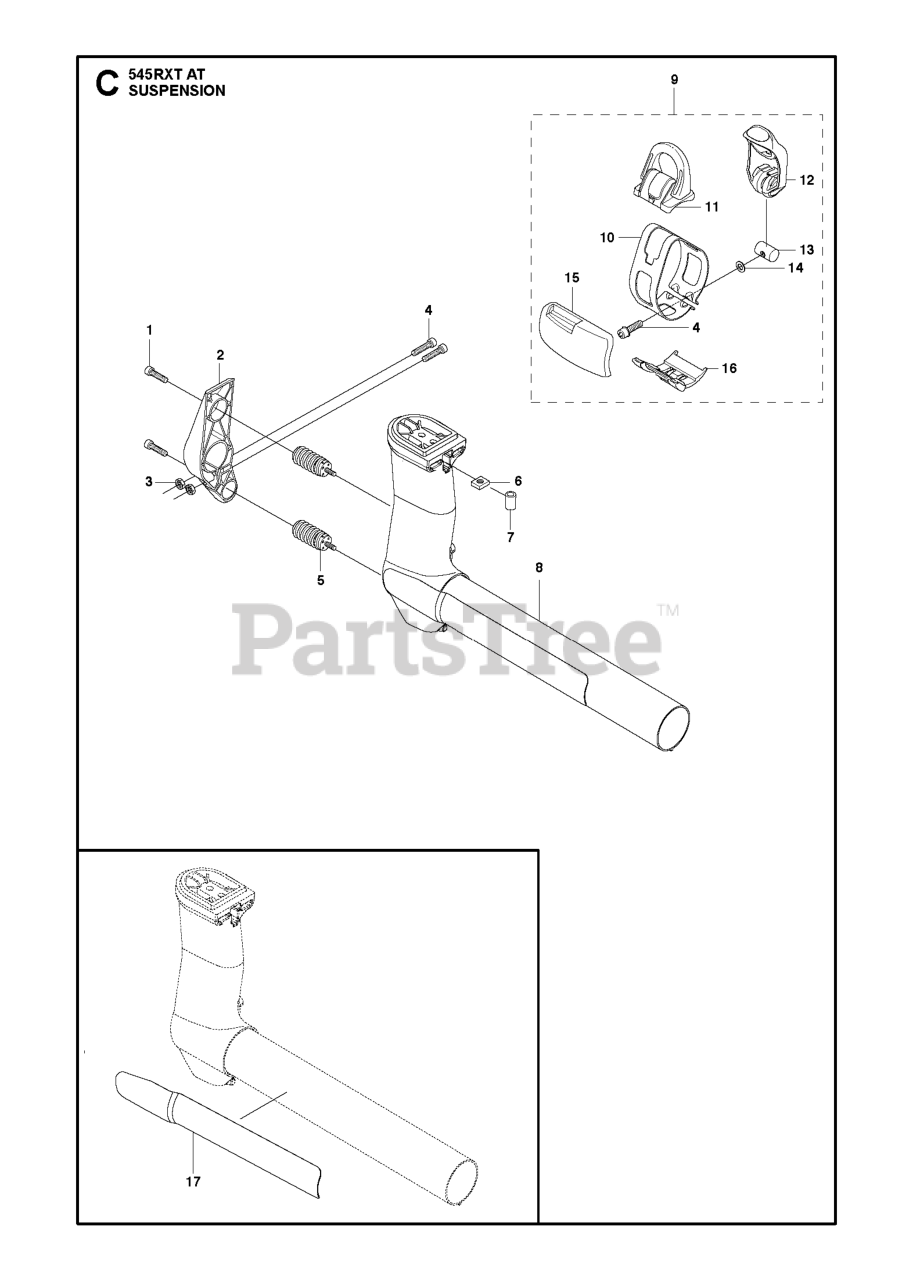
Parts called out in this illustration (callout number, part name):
2	HOLDER ANTIVIBRATION
5	ANTIVIBRATION ELEMENT ASSY
8	SUSPENSION
14	WASHER 5.3X12
15	WEAR PROTECTION
16	GUIDE RAIL
17	WEAR PLATE ASSY
